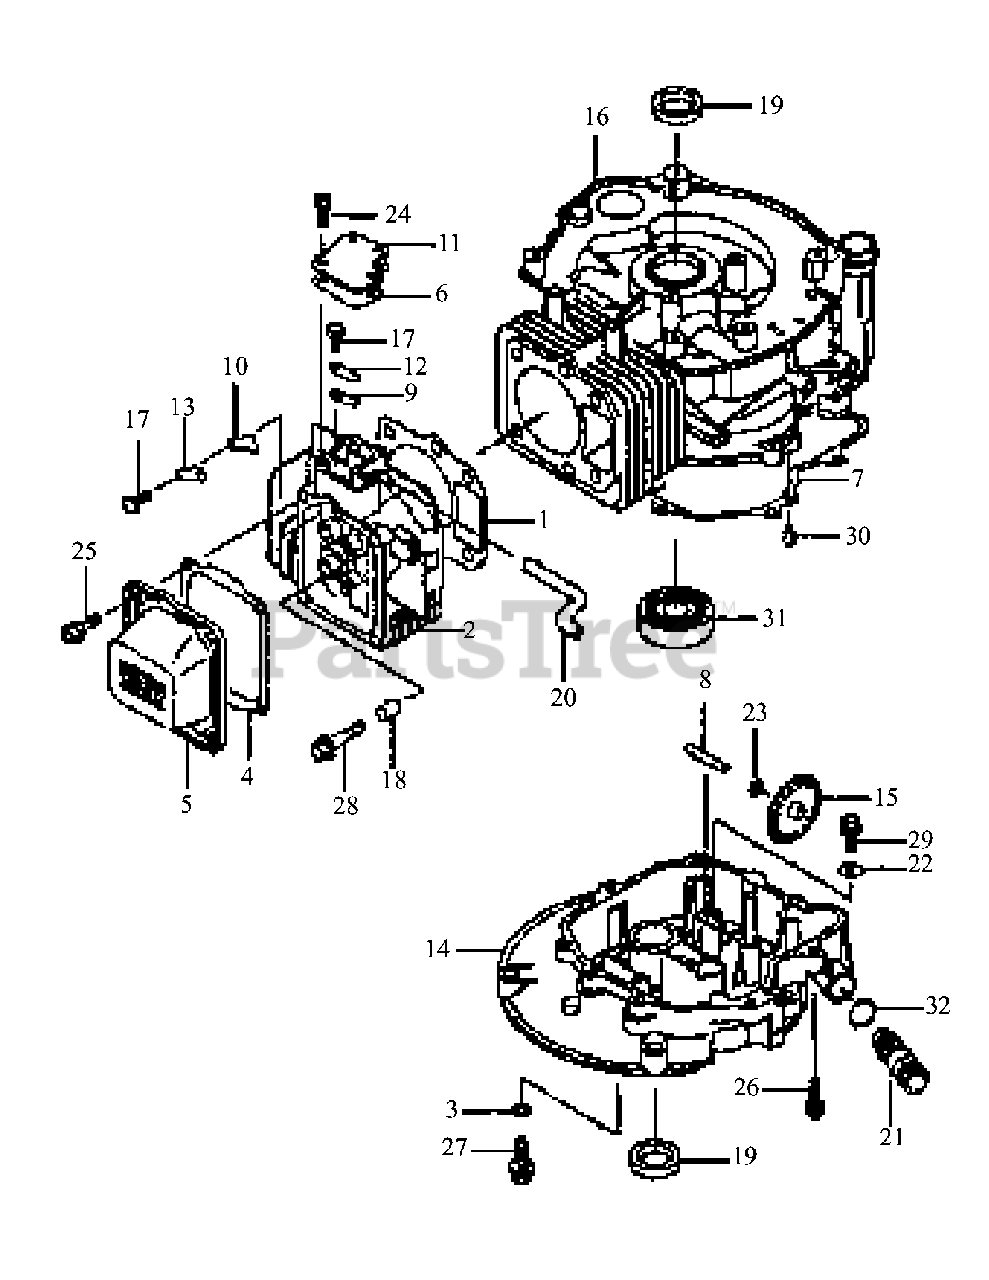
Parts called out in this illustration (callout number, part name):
2	Cylinder Head complete
4	Gasket, Rocket Case
6	Gasket, Cover
7	Gasket, Crankcase Cover
14	Cover-Crankcase
16	Crankcase, Complete
20	Tube
22	Washer, 5x16x0.8
23	Washer, 6x12x1.6
24	Bolt, Flange
25	Bolt, Flange
26	Bolt, Flange
27	Bolt, Flange
28	Bolt, Flange
31	Bearing, Ball
